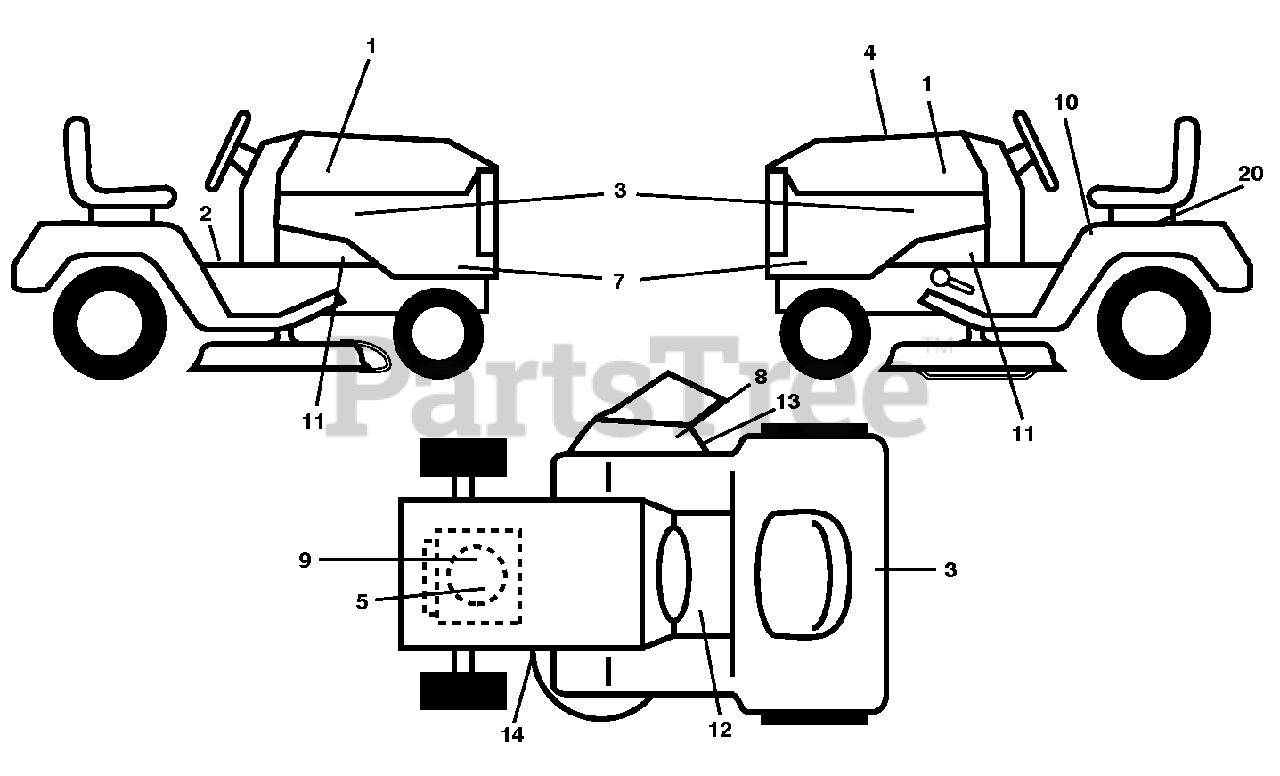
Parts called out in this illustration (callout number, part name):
2	DECAL.PARKING.BRAKE.SADDLE.LT
3	DECAL HOOD
5	DECAL.ENGINE.WARNING
8	DECAL.CUTFINGER.CE.02
9	DECAL.ENG.BS.3125SER.PB.279738
10	DECAL.READ.OWN.MAN.SYMBOL.LT
11	DECAL.CHASSIS.HOT.MUFFLER
12	DECAL.FNDR.SDLE.BRAKE.CLUTCH.6
13	DECAL.DFLCTR.WARNNG.CTFNGR.SYM
14	DECAL.DECK.SCH.36,38,94.NONCR
20	DECAL BTRY SYMBOLS
